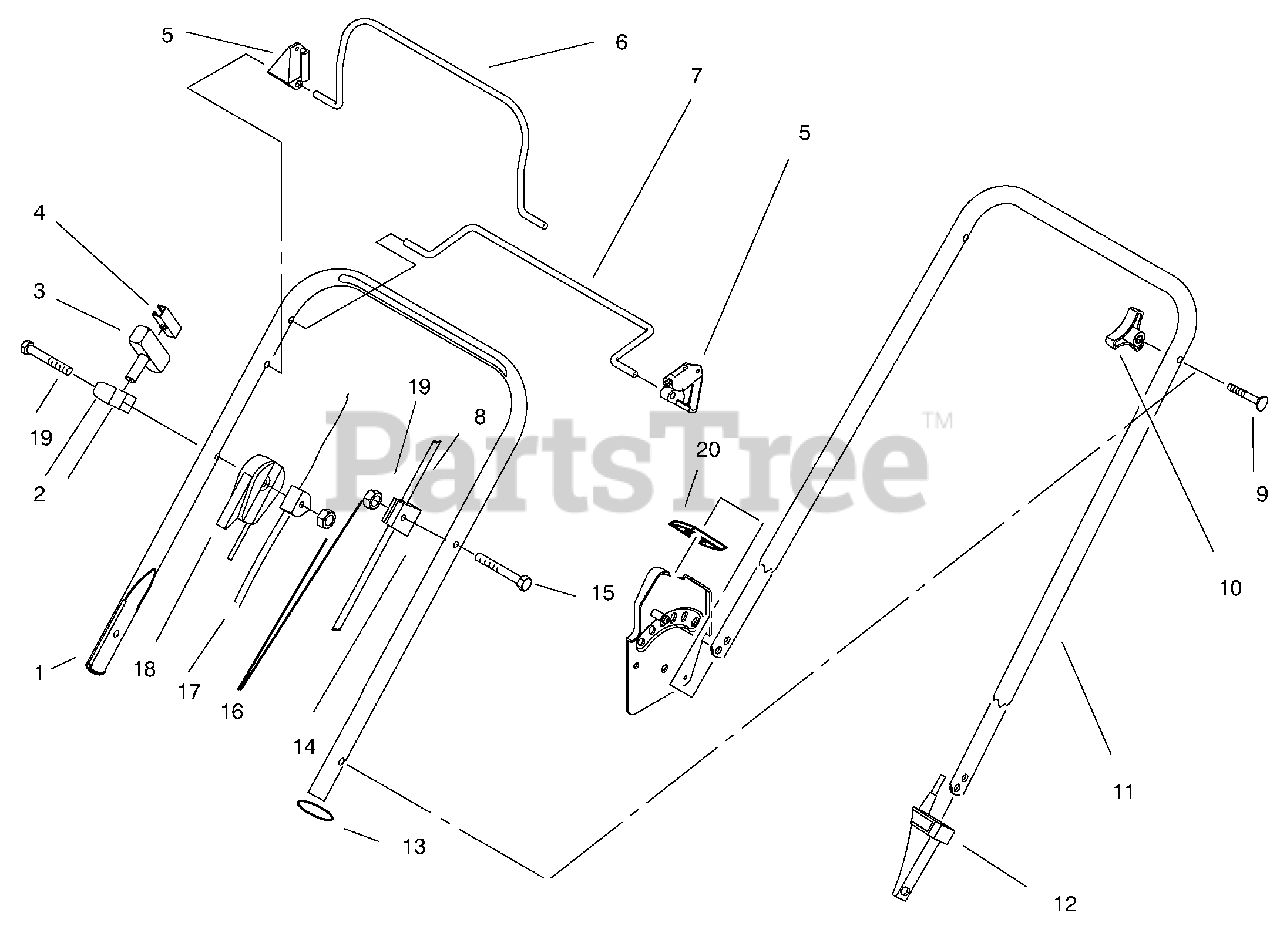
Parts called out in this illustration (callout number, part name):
1	Handle-Upper
2	Guide-Rope
3	Handle-Starter
4	Clip-Rope Insert
5	Stop-Pivot (Qty 1 Model No. 10202)(Qty 2 Model No. 10302)
6	Bail-Brake
7	Bail-Control (Model No. 10302 Only)
8	Cable-Traction
9	Screw-Handle
10	Knob-Handle
11	Handle-Lower
12	Anchor-Cable, (Lower)(Model No. 10302 Only)
13	Tie Strap
14	Anchor-Cable, (Upper)(Model No. 10302 Only)
15	Screw (Model No. 10302 Only)
16	Nut (Qty 1 Model No. 10202)(Qty 2 Model No. 10302)
17	Cable-Brake
18	Cable-Throttle
20	Handle-Guard
